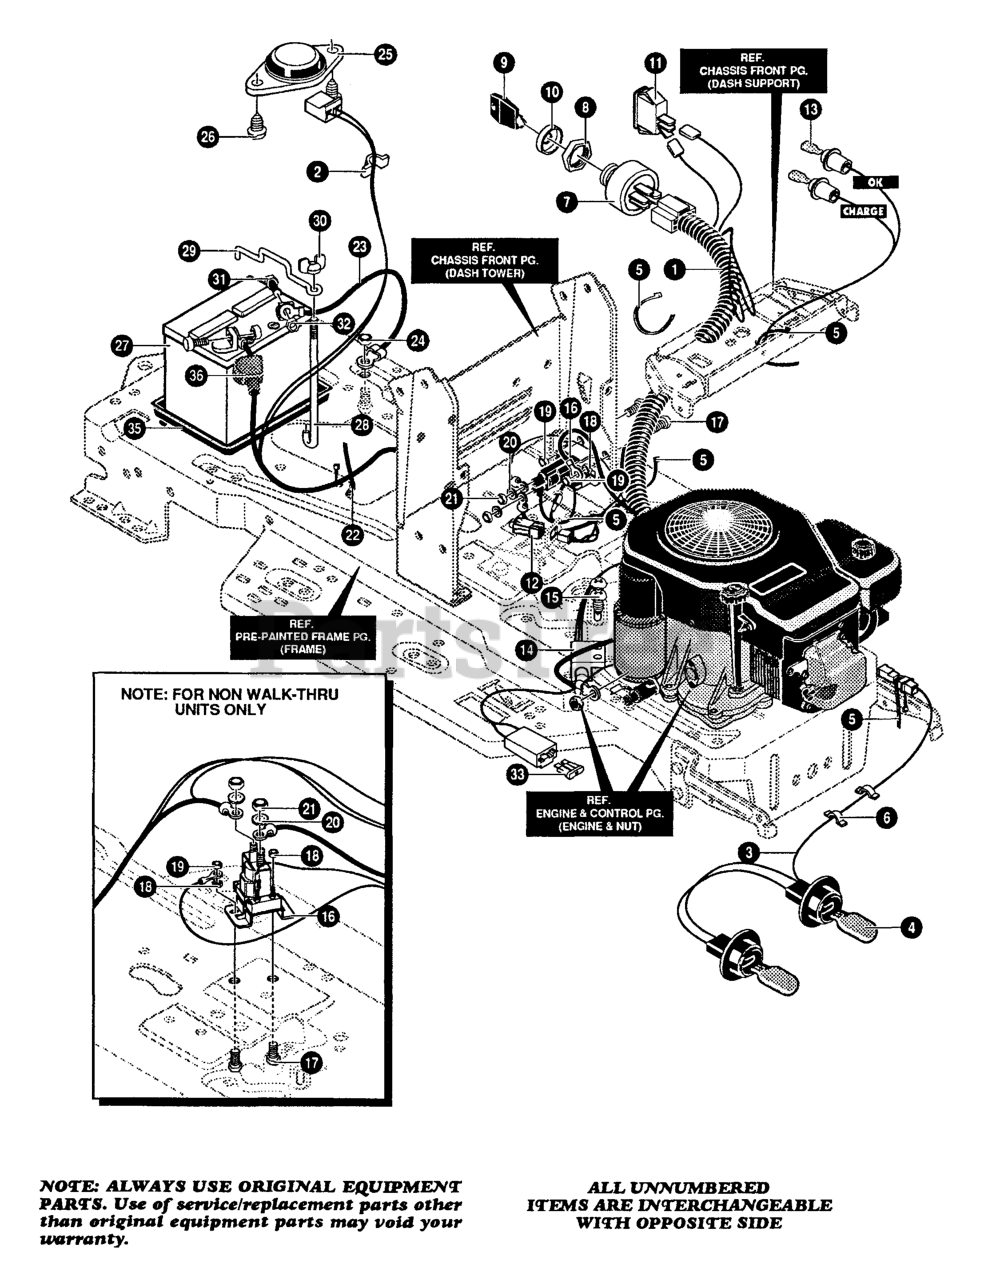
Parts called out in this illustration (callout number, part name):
1	HARNESS
2	PRESS CLIP, 1.380LG .255ID
3	ASSY, LIGHT WIRE-1/4 TURN
4	BULB, HEADLAMP
5	TIE, CABLE BLACK NYLON 5.62L
6	PRESS CLIP, 1.380LG .255ID
7	SWITCH-IGN. (AFTER FIRE) 3 POSN
8	NUT, 5/8-8 ACME DELTA FOR BOOT
9	KEY, IGNITION
10	BOOT, IGN SWITCH
11	LIGHT SWITCH PANEL MNT
12	SWITCH, DOUBLE POLE NO/NC GRAY
13	BULB, INDICATOR
14	SWITCH, SCR MNT DP NC NO BLK
15	SCREW, #12 x .50 PHPNHTAP
16	SOLENOID
17	SCREW, 1/4-20 x .75 HXSEMMA
18	NUT, 1/4-20 REGHEXCTRLK
19	NUT, 1/4-20 REGHEXKEPS
20	WASHER, EXLK .320 x .61 x .03
21	NUT, 5/16-24 REGHEX
22	TIE, CABLE BLACK NYLON 5.62L
23	WIRE, GROUND, 12.5"
24	NUT, 5/16-18 HEXKEPS
25	SWITCH, SEAT
26	SCREW, 1/4-20 x .38 PHPNHMA
27	BATTERY, 12V 7 PLATE (DRY BATTERY)
28	ROD, BATTERY
29	ROD, BATTERY, TOP
30	NUT, WING 1/4-20 NYLON
31	SCREW, 1/4-20 x .75 HHC
32	NUT, 1/4-20 REGHEXKEPS
35	TRAY-BATTERY
36	BOOT, BATTERY MURRAY #54148
